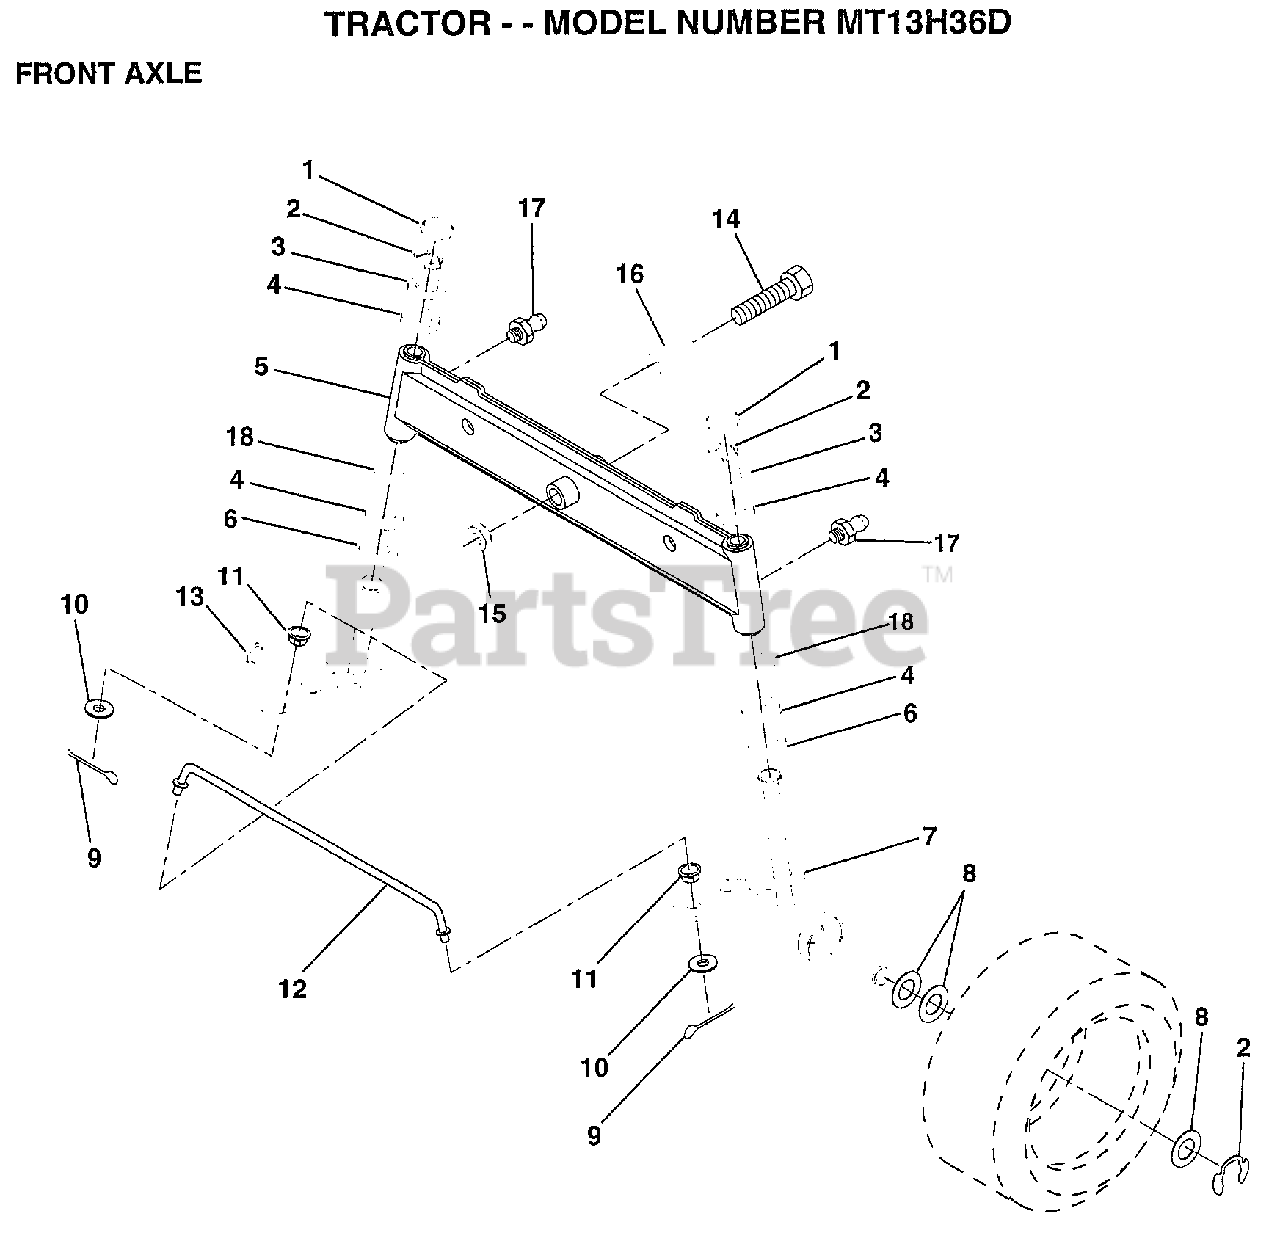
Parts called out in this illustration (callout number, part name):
1	CAP
2	RING
3	WASHER
4	COL. SRTG. BEAR.
5	AXLE ASM FRONT
6	WASHER .T
7	SPINDLE.ASSY.RH
8	WASHER
9	COTTER PIN
10	WASHER
11	BUSHING.DRAGLINK
12	TIE ROD
13	SPINDLE.ASSY.LH
14	BOLT HEX 5/8-11
15	"NUT-LOC,FLANGE LT"
16	BEARING
17	ZERK M
18	WASHER
